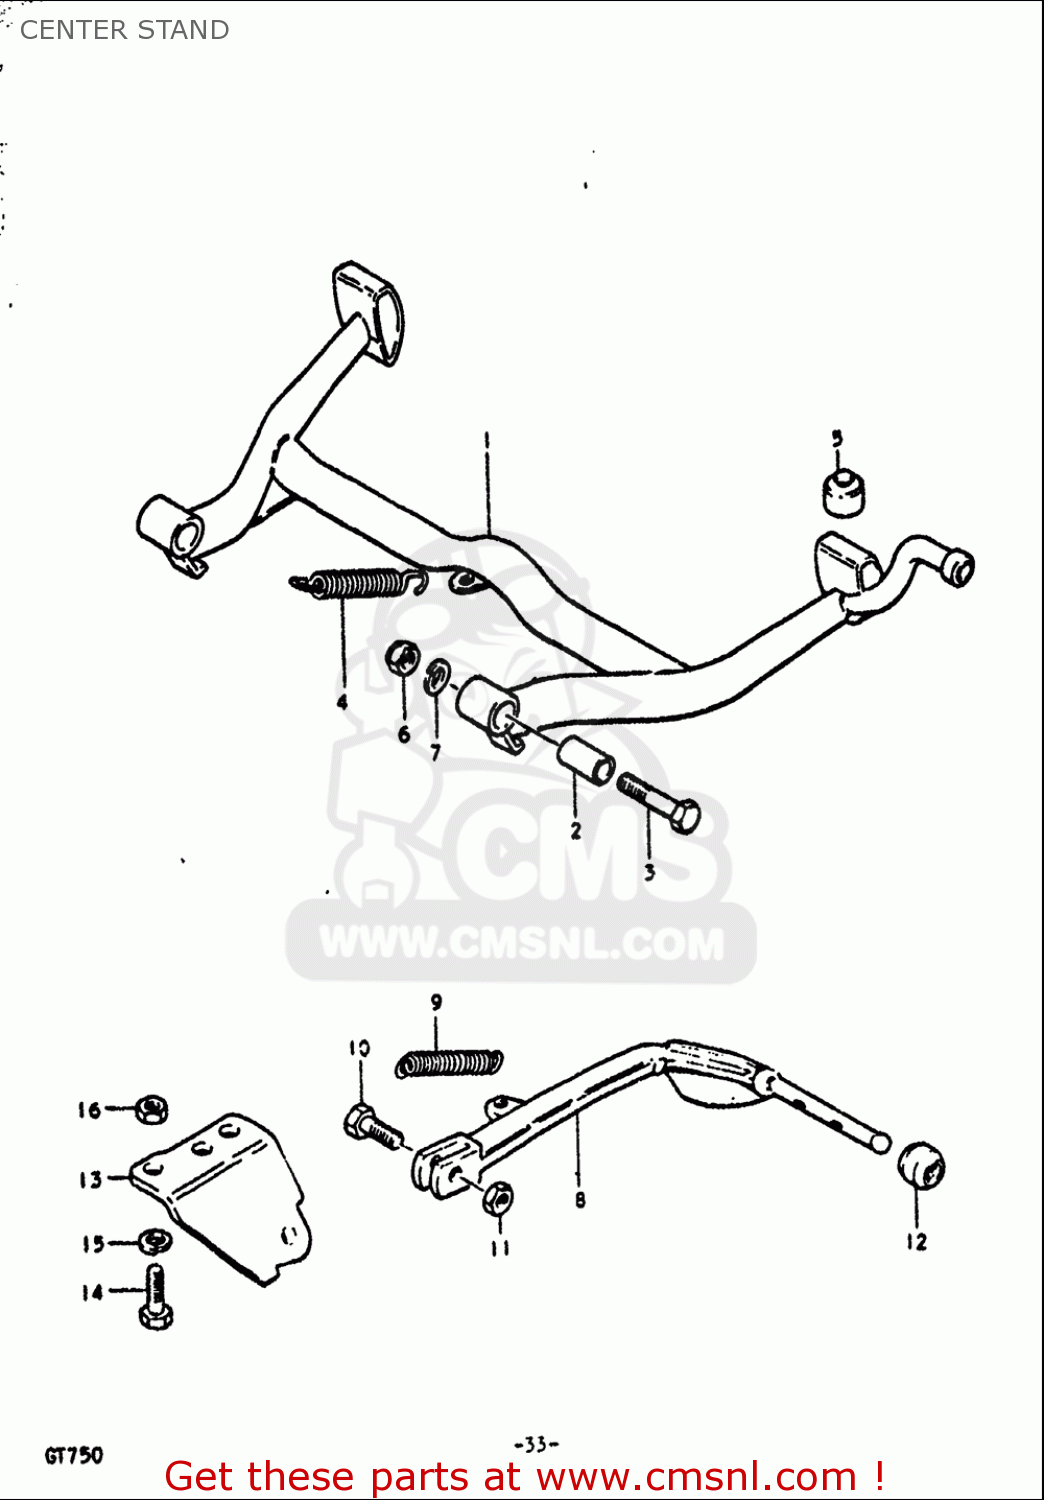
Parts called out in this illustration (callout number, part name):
2	SPACER(10.5X16X30)
3	BOLT(10X48)
4	SPRING
5	CUSHION
6	NUT
7	WASHER,LOCK
9	SPRING
10	BOLT(10X27)
11	NUT
12	CUSHION
14	BOLT(10X27)
15	WASHER,LOCK
16	NUT
